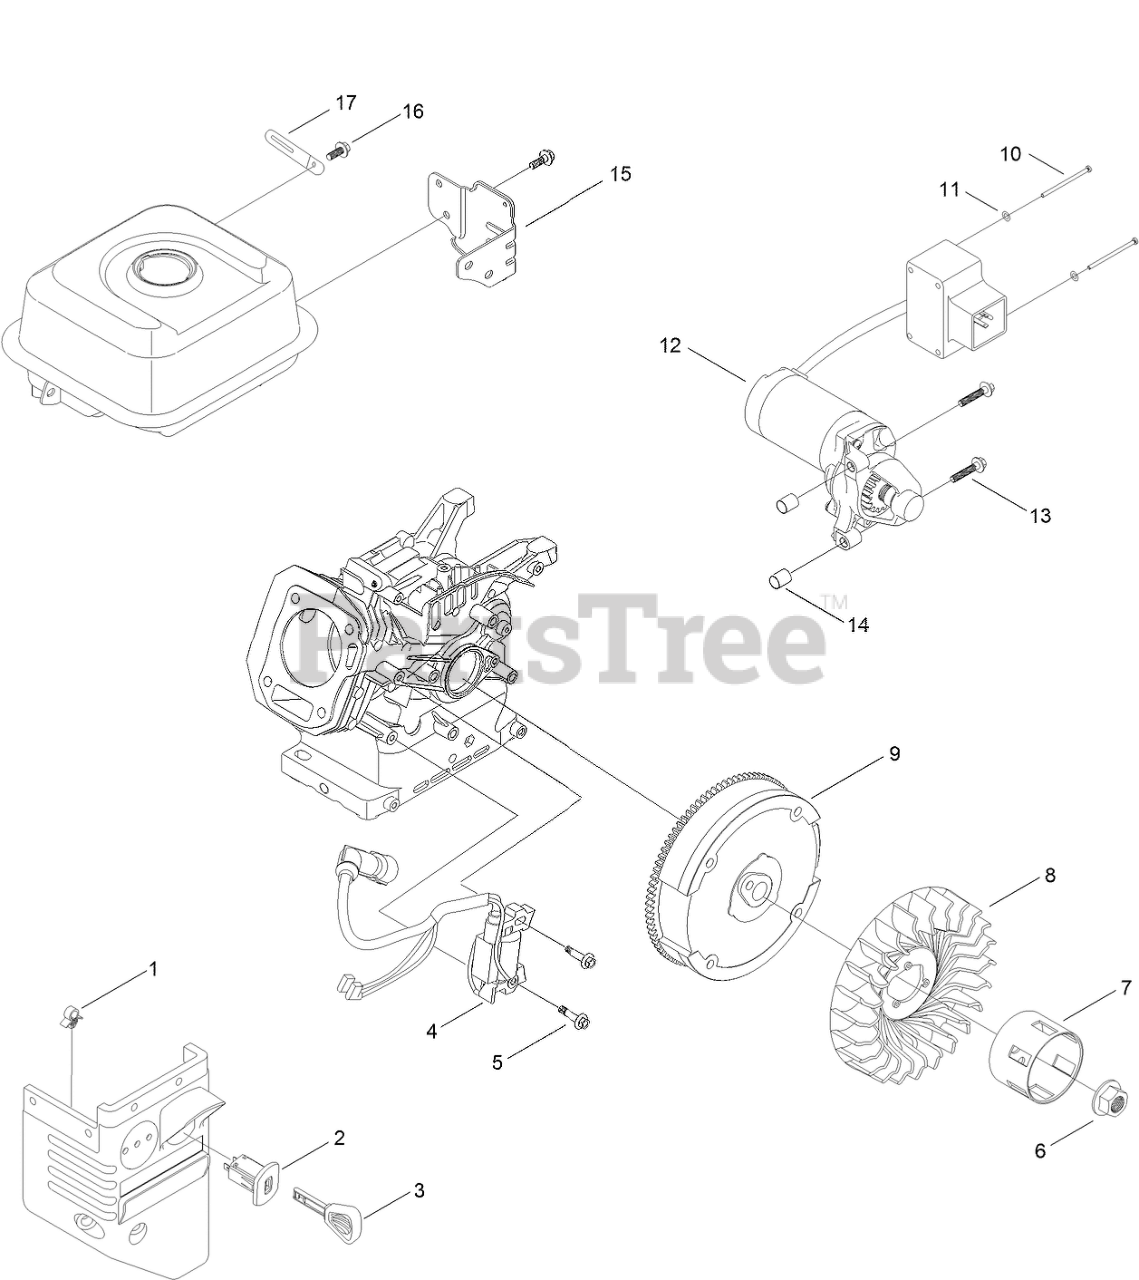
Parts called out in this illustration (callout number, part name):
2	SWITCH-KEY
4	IGNITION COIL ASM
5	SCREW-HHF
6	NUT-FLANGE
7	CUP-STARTER
9	FLYWHEEL
10	SCREW-BHP
11	WASHER-PLAIN
12	MOTOR-STARTER
13	SCREW-HHF
14	PIN-DOWEL
15	BRACKET-BOX, SWITCH
16	SCREW-HHF
17	CLIP-HARNESS, WIRE
